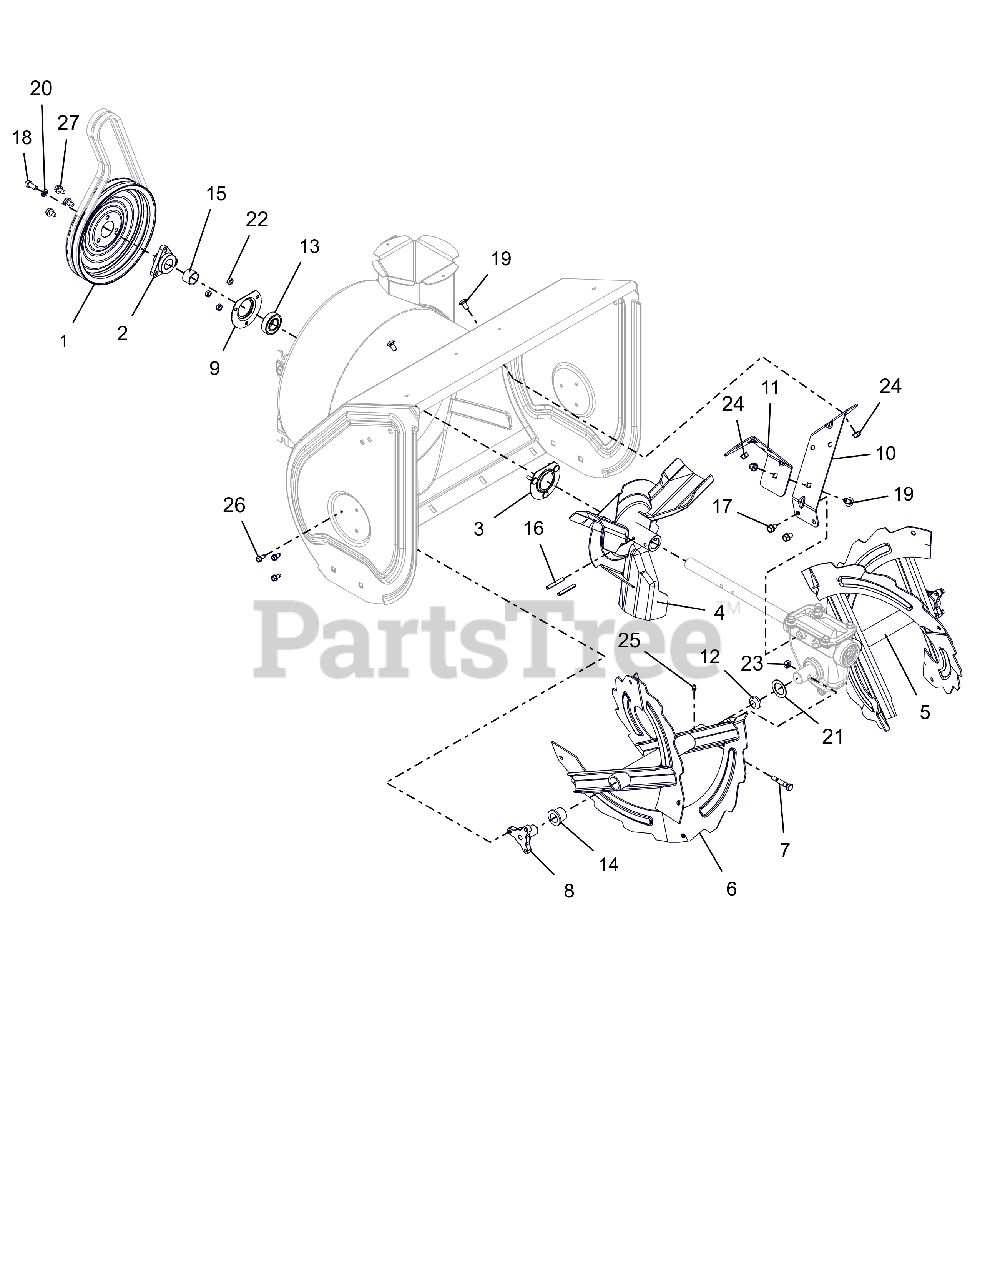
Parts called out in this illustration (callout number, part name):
1	PULLEY, SPIN FORM DUAL GROOVE
2	PULLEY HUB, D-BORE .87 DELUXE
3	BEARING FLANGE
4	IMPELLER, 3 BLADE-14"
5	RAKE, LH W/ZERK - 24"
6	RAKE, RH W/ZERK - 24"
7	SHEAR BOLT SERVICE ASSEMBLY
8	SUPPORT, RAKE BUSHING
9	BEARING FLANGE
10	BRACKET, GEARCASE SUPPORT - LH
11	BRACKET, GEARCASE SUPPORT - RH
12	PLUG, RAKE TUBE
13	BRG-BALL .876 X 1.750 X .50
14	BSHG-FLG, NY.778 ID X 1.018 OD
15	BSHG,SPCR .895X1.065X.693
16	PIN-ROLL .250X1.75
17	BLT, SEMS .31-18X.50 G5 ZCC
18	BLT, HEX .31-24X.750 G5 ZCC
19	BLT,RHSSN.31-18X.625 G5 ZCCP30
20	WSHR, LK-HVY .312X.097 ZCC
21	WSHR, FLT 1.010X1.505X.062 ZCC
22	NUT,LK-CTR .25-20 GA ZCC
23	NUT,LK-CTR .31-18 GA ZCC
24	NUT-LK-TOP-FLG .312-18 GF ZCC
25	ZERK,FITTING .25X.125 DRIVE IN
26	SCR-TAP .25-20X.50 HWH ZCC
27	SCR,TAP .312-18X.50 HWH TR ZCC
